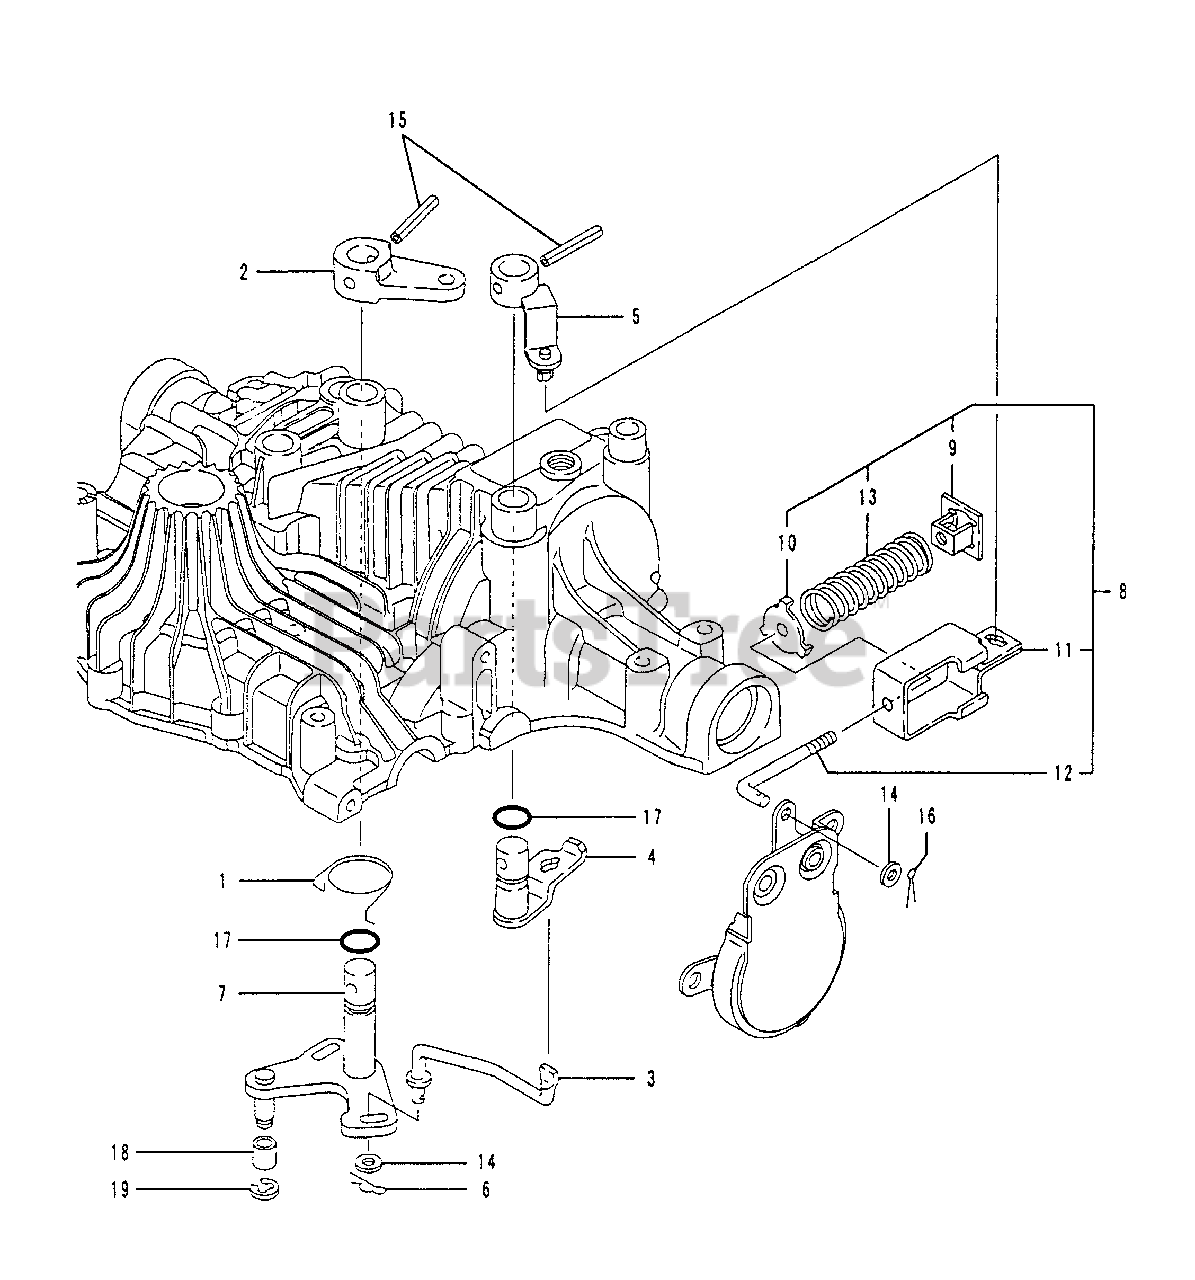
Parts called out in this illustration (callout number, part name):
1	RETURN SP (BRAKE
4	ARM A(BRAKE
5	ARM B(BRAKE
7	SHAFT (BRAKE
8	BRAKE ROD CMP
9	ADJUSTER CMP
10	SPRING GUIDE
11	HOLDER(SPRING
12	ROD (ADJUSTER
13	SPRING
15	PIN 6.0A X.40
16	PIN 2.0 X 20
17	PACKING P 12
